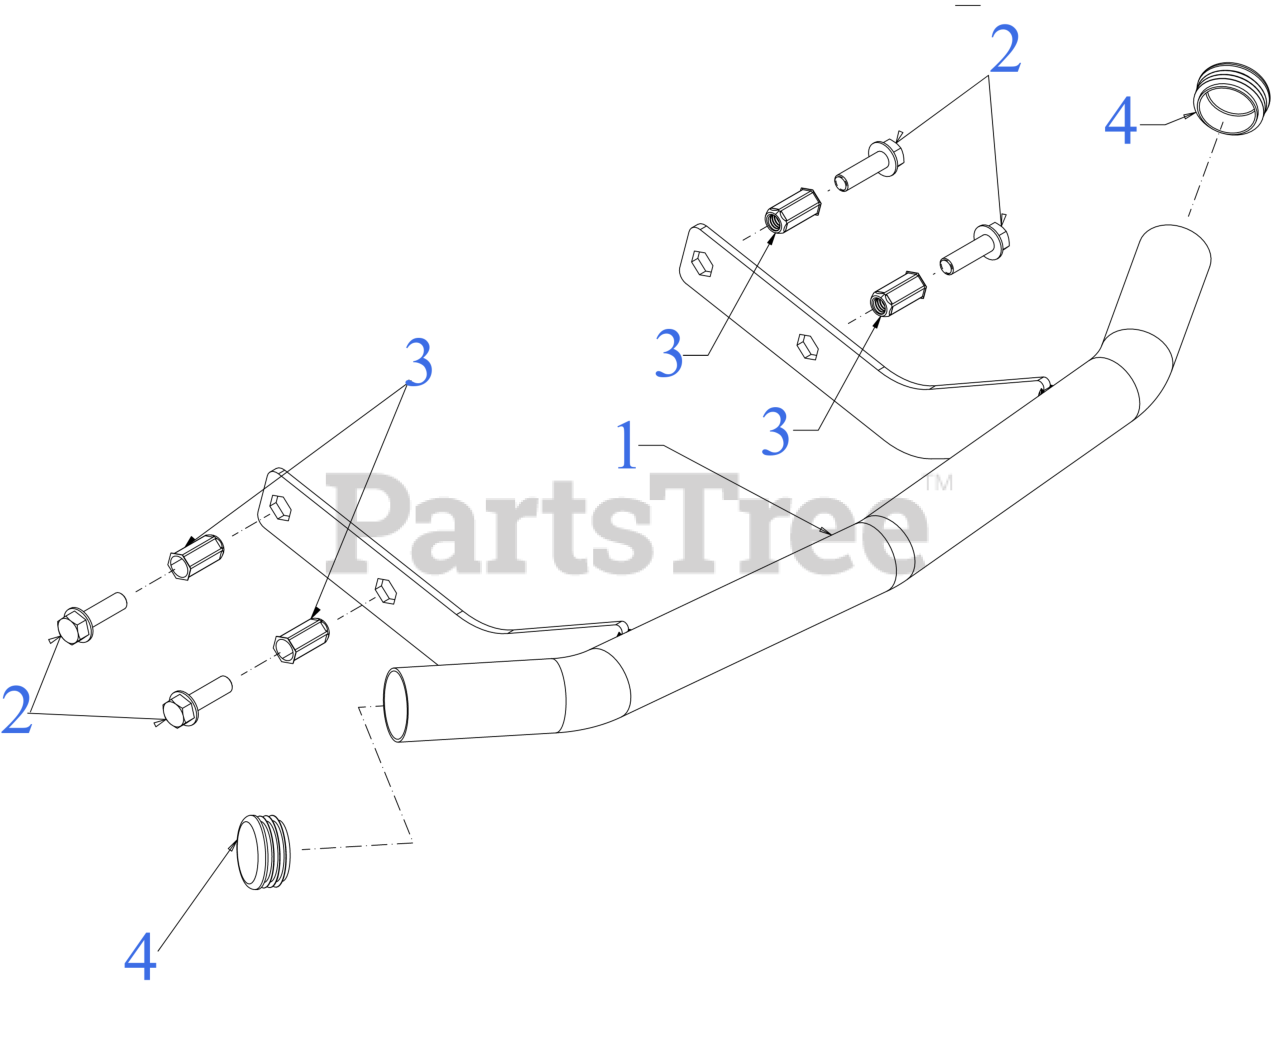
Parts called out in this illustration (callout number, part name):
1	BUMPER ASSEMBLY (BLACK)
2	SCREW 3/8-16 x 1.25 GR5
3	NUT RIVET 3/8-16
4	BUMPER CAP
